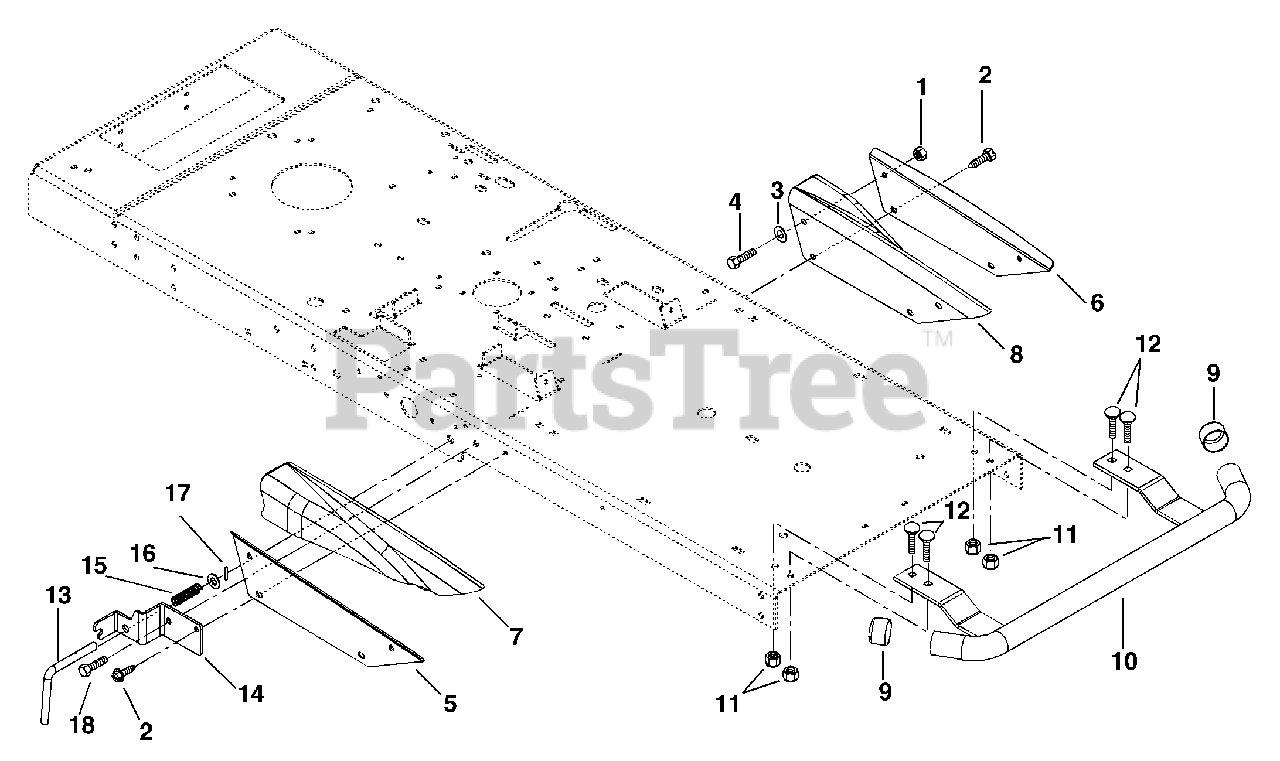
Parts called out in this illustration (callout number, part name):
1	Nut-Locking-Nylon .312-18 Grade 5
2	Screw-Tapping.312-18 x .75 Grade 5
3	Washer-Flat-Steel .344 x .688 x .065
4	Bolt-Hex .312-18 x .75 Grade 5
5	Bracket-Rail Support-Right Hand
6	Bracket-Rail Support-Left Hand
7	Rail-Side-Right Hand
8	Rail-Side-Left Hand
9	Cap-Sleeve
10	Weldment-Bumper
11	Nut-Locking-Nylon .375-16 Grade 5
12	Bolt-Round Head Square Neck .375-16 x 1.00 Grade 5
13	Pin-Index
14	Bracket-Stop
15	Spring-Compression
16	Washer-Flat-Steel .531 x 1.06 x .095
17	Pin-Roll
18	Bolt-Hex .38-16 x 1.00 Grade 5
